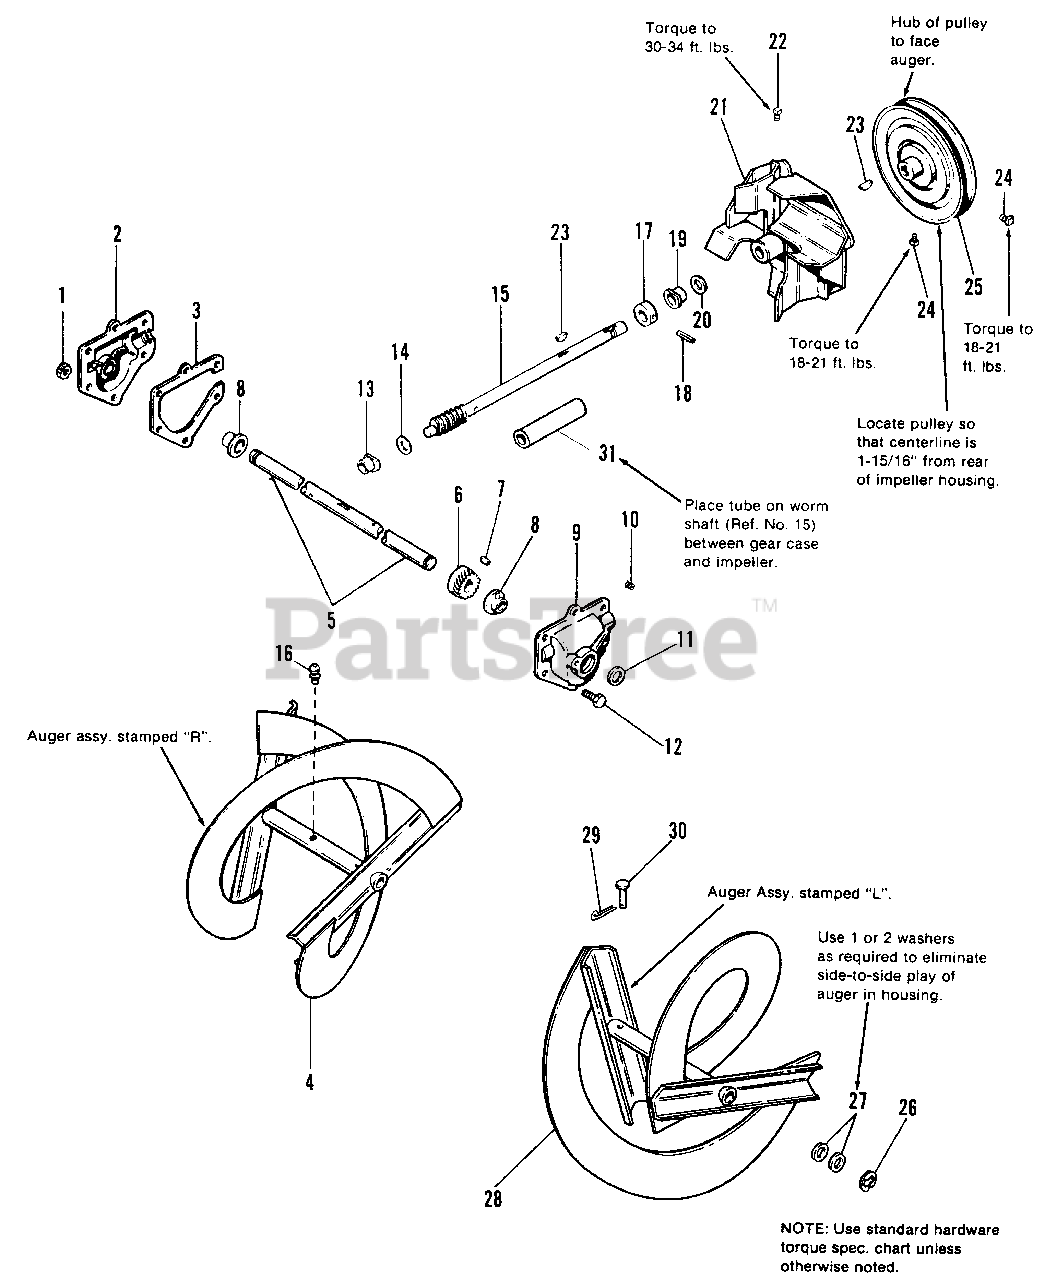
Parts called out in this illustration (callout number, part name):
1	NUT, Lock. 1 /4-20 (Qty . 5 on 1691011 & 1691181)
2	GEAR CASE ASSY., R.H. (1691011 & 1691181 only)
2	GEAR CASE ASSY., R.H. (Incl. Ref. No. 8, Qty. 1) (1691411, 1691413, 1691414 only)
3	GASKET (1691011 & 1691811 only)
4	AUGER ASSY., R.H. (Incl. Ref. No. 16, Qty. 1)
5	AUGER, Shaft
7	KEY, Woodruff
9	GEAR CASE ASSY., L.H. (1691011, 1691181 only)
10	PLUG, Pipe, 1/8-NPT
12	CAPSCREW, Hex, 1 4-20 x 7/8 (Qty. 5 on 1691011 & 1691181)
14	WASHER, Thrust
16	GREASE FITTING
17	COLLAR, Thrust
18	PIN, Driv-lok, 3/16 x 1-1/2
20	SEAL, Oil (1691011 & 1691181 only)
21	IMPELLER ASSY.
22	SETSCREW, Sq. Hd., 3/8-16 x 1/2
23	KEY, Woodruff, 3/16 x 3/4
24	SETSCREW, Sq. Hd., 5/16-18 x 1/2
25	PULLEY, Input, Auger
26	RING, Retaining
27	WASHER (1691011, 1691181) (Use as required on 1691411, 1691413, 1691414)
28	AUGER ASSY., L.H. (Incl. Ref. No. 16, Qty. 1)
29	PIN, Cotter, 3/4
30	PIN, Shear
